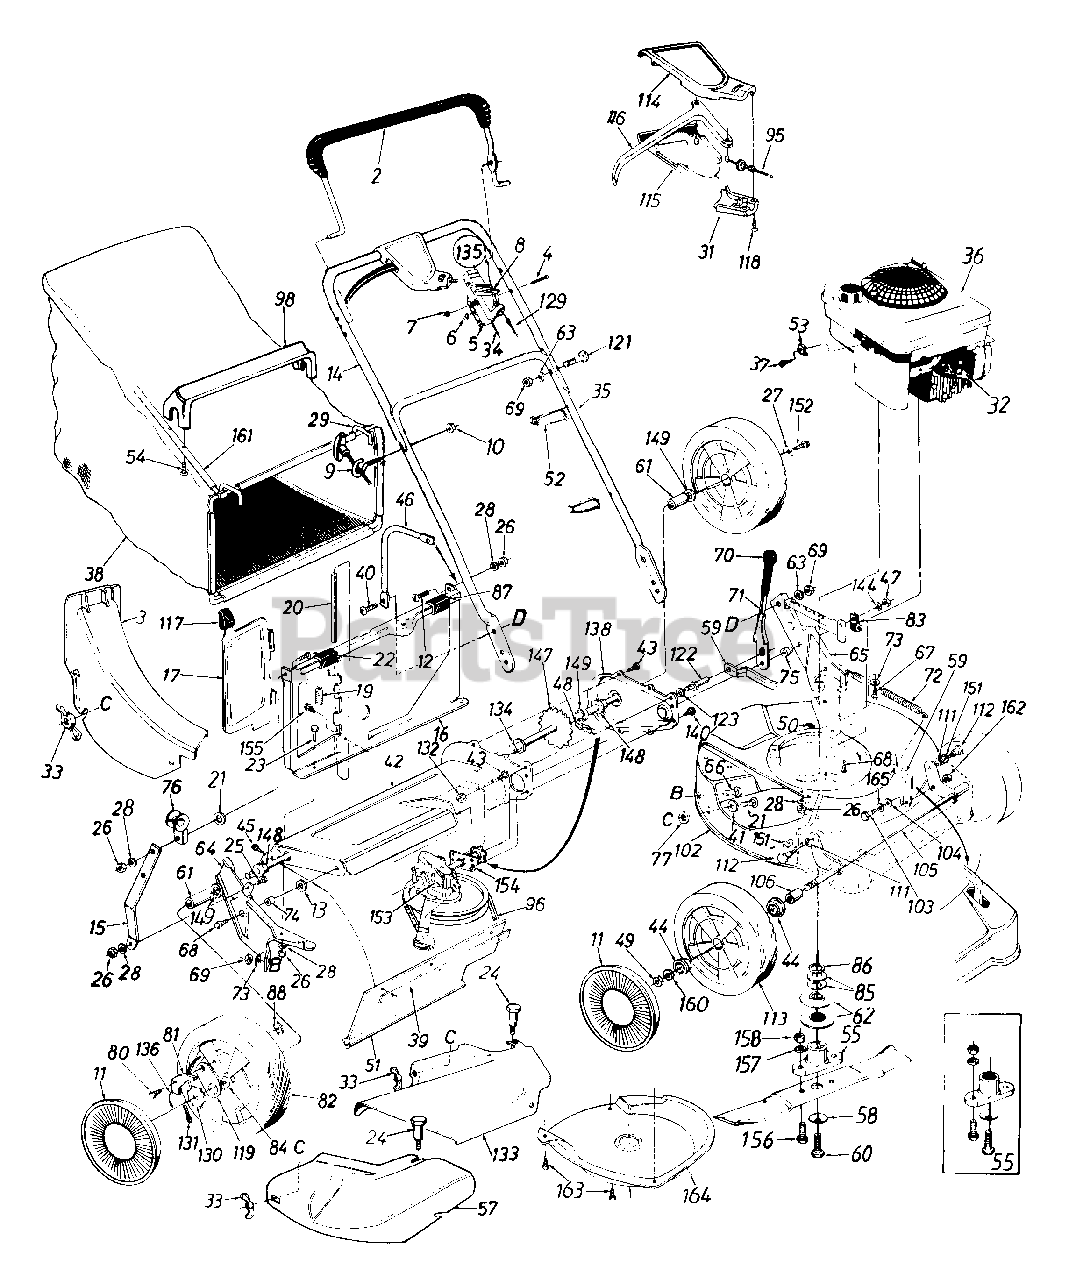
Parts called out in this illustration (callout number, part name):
2	Control Handle Ass'y.- L.H.
3	Rear Discharge Chute Ass'y.
4	Oval C-Sunk Scr.
5	Throttle Body
6	Spr. Wash..66" I.D.
7	Hex L-Nut 1/4-20 Thd.
8	Throttle Lever
9	Rope Guide
10	Hex L-Nut 1/4-20 Thd.
11	Hub Cap
12	Truss Mach. Scr. 1/4-20 x .62"
13	Fl-Wash..383" I.D. x 1" O.D.
14	Upper Handle - Painted
19	Torsion Spring
20	Pivot Pin
21	Carriage Bolt 1/4-20 x .62"
22	Truss Mach. Scr. 1/4-20 x 3/4"
23	Hex Bolt 1/4-20 x .50" Lg.
24	Shoulder Bolt .312 Dia. x .18 Lg.
25	Hex Bolt 1/4-20 x .62" Lg.
26	Hex Nut 1/4-20 Thd.
27	Bell-Wash. 1/4" I.D.
28	L-Wash. 1/4" I.D.
31	S.P. Control Cover
32	Spark Plug Insulator
33	Wing Nut w/Washer
34	Throttle Control Wire 61"
35	Lower Handle - Painted
37	Hex Self-Tap Scr. #10-32 x .62"
38	Grass Bag
39	Retaining Strip
40	Truss Mach. Scr. 5/16-18 x .75"
41	Fl-Wash..344" I.D. x .62"
44	Flange Ball Bearing 1/2" I.D.
45	Hex AB-Tap Scr. 1/4 x .62"
46	Catcher Panel Support Arm
47	Hex Patch L-Nut 3/8-24 Thd.
48	#48 Chain .500" Pitch x 30 Links
49	Hex Ins. Top L-Nut 3/18-16 Thd.
51	Rear Flap 3.75" x 17.30" Lg.
52	Cable Tie
53	Cable Clamp
54	Hex AB Scr. #12 x 1.25" Lg.
55	Blade Adapter Kit
57	Mulching Plug
58	Bell-Wash..39" I.D.
59	Height Adj. Connecting Arm
60	Hex Bolt 3/8-24 x 1.5" Lg. (Grade 5)
61	Spacer .513" I.D. x .703" O.D. x .69" Lg.
62	Lower Pulley Half
63	L-Wash. 5/16" I.D.
64	R.H. Handle Wheel Brkt. Ass'y.
65	L.H. Handle Wheel Brkt. Ass'y,
66	Carriage Bolt 5/16-18 x .62"
67	Hex Wash. Hd. B-Tap Scr. 5/16-18
68	Hex Wash. Hd. TT-Tap Scr. 3/8-16
69	Hex Nut 5/16-18 Thd.
71	Height Adj. Lever
72	Extension Spring .75" O.D. x 8"
73	Bell-Wash. 5/16" I.D.
74	Spacer
75	Shld. Spacer .500" Dia.
76	Rope Guide
77	Bolt Retainer 1/4 x .50" O.D.
80	Shld. Scr..342" Dia. x .268
81	Pawl
82	Wheel Ass'y. Comp.
83	Clamp
84	Upper Pulley Half
85	Bell-Washer 7/8" I.D.
86	Crankshaft Spacer
87	Panel Clip
88	Weld L-Nut 1/4-20 Thd.
95	S.P. Cable
96	"V"-Belt
98	Bag Handle
102	21" Deck Ass'y.
103	Shld. Bolt .5" Dia. x .295
104	Bell-Wash..515" I.D. x 1.0" O.D.
105	Front Axle Ass'y.
106	Sleeve .526" I.D. x .690" O.D. x .880" Lg.
111	Intern. L-Wash. 3/8 I.D.
112	Shld. Bolt .575" Dia. x .42
114	Self-Propelled Control Cover
115	Self-Propelled Control Cover
116	Control Lever
117	Door Grip
118	Fl-"C"-Sunk Hd. Tap Scr. #10 x .75" Lg.
119	Pawl Plate
121	Curved Carr. Bolt 5/16-18 x 1.38" Lg.
122	Shld. Pin 3/8-24 x 1.43" Lg.
123	L-Wash. 3/8" I.D.
129	Control Cable 47" Lg.
130	Ratchet Wheel 1.62" O.D.
131	Cotter Pin 1/8" Dia. x 1.00" Lg.
132	Hex Jam Nut 3/8-24 Thd.
133	Side Chute Deflector Ass'y.
134	Hex Flange Bearing
136	Spring - Nylon
144	Fl-Wash..385" I.D. x .87"
147	Rear Shaft Ass'y. 21.94" Lg.
148	Hex Flange Bearing .506" I.D. Plastic
149	Fl-Wash..531" I.D. x .930"
151	Flanged Nyliner Brg.
152	Hex Bolt 1/4-20 x .62" Lg. (Grade 5)
153	Transmission Comp. (See Breakdown)
155	Hex B-Tap Scr. #10 x 38
156	Hex Scr. 3/8-24 x 1.0" Lg.
157	L-Wash. 3/8" I.D.
158	Hex Nut 3/8-24 Thd.
160	Fl-Wash. .385" I.D. x .87" O.D.
162	Hex Jam Nut 3/8-16 Thd.
163	Hex Wash. Hd. Tap Scr. 1/4 x .5" Lg.
164	Mulching Baffle
165	Fl-Wash. .51" I.D. x .75"
